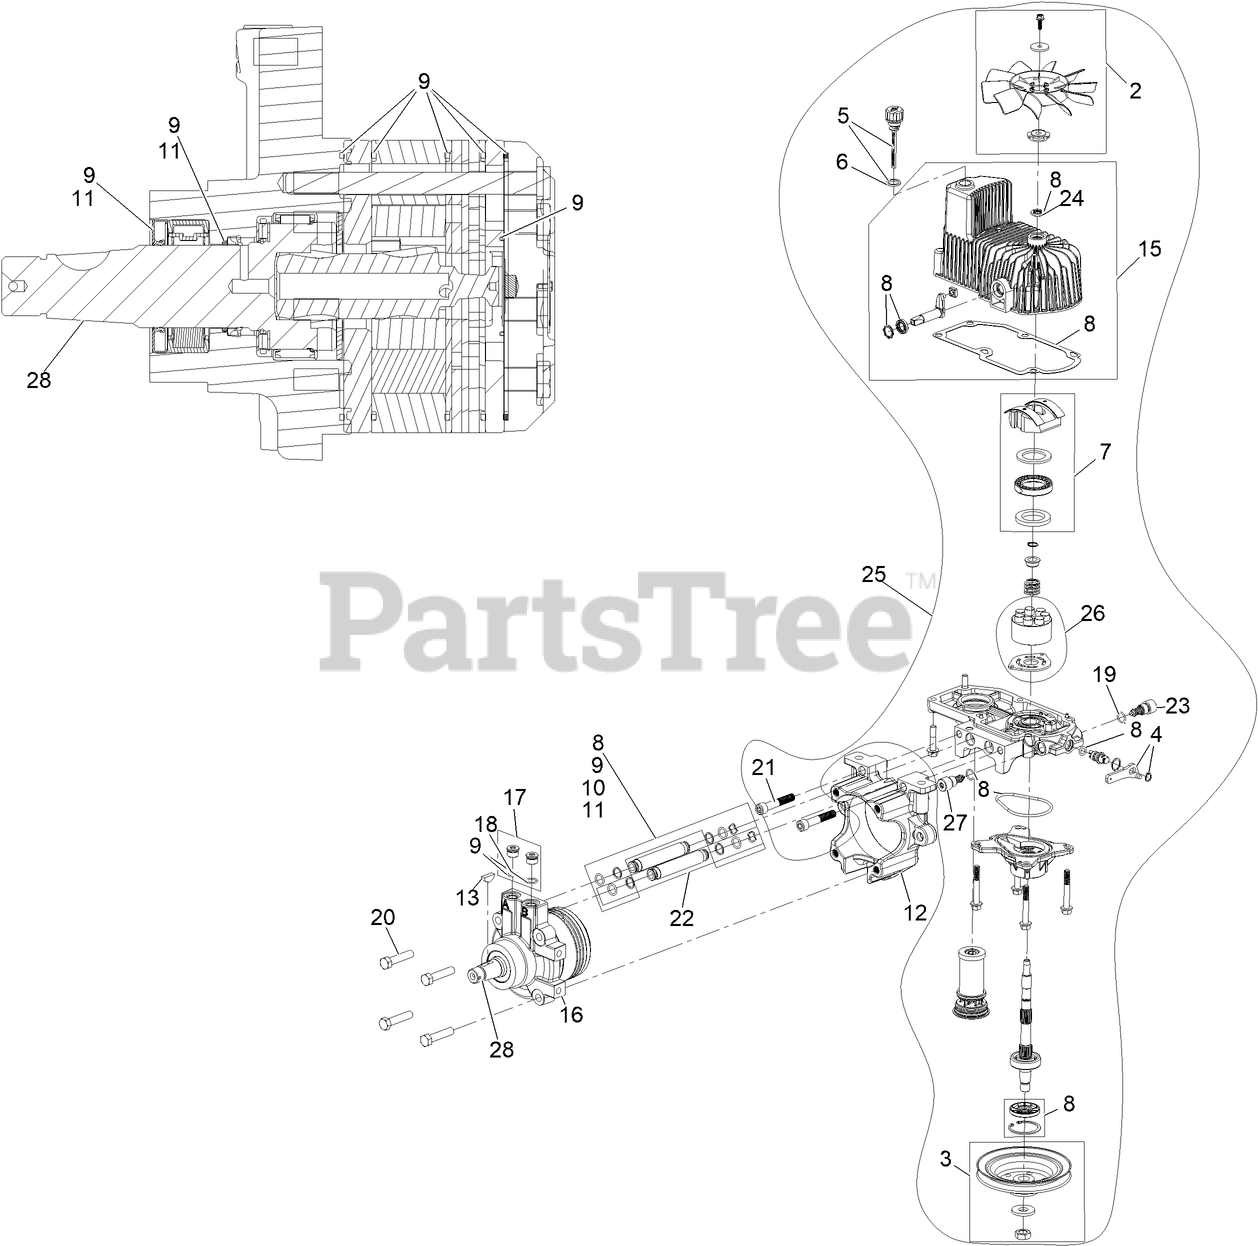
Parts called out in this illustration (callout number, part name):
2	KIT, 7.8 IN FAN
3	PULLEY KIT
4	HANDLE-BYPASS VALVE, HYDRO
5	DIPSTICK-HYDRO W/GASKET
6	GASKET-DIPSTICK, HYDRO
7	SWASH BLOCK KIT
8	KIT, PUMP SEAL
9	MOTOR SEAL KIT
10	TUBE SEAL KIT
11	OUTPUT SHAFT SEAL KIT
12	NOSE CUP-UHT
13	KEY-WOODRUFF
15	KIT, HOUSING-HYDRO LH
16	HYD MOTOR,280CC LH SEALED
17	MAGNETIC PLUGS SERVICE KIT
18	O-RING
19	O-RING-CHECK VALVE
20	SCREW HH
21	SCREW-HSH
22	HYDRAULIC TUBE KIT
23	SHOCK VALVE, 16CC HYDRO
24	SEAL-FAN DRIVE
25	KIT, PUMP SECTION 16CC LH
26	KIT - 16CC PORT PLATE,ROTATE GRP
27	SHOCK VALVE ORIFICED 3300
28	OUTPUT SHAFT- TL UHT MOTOR
